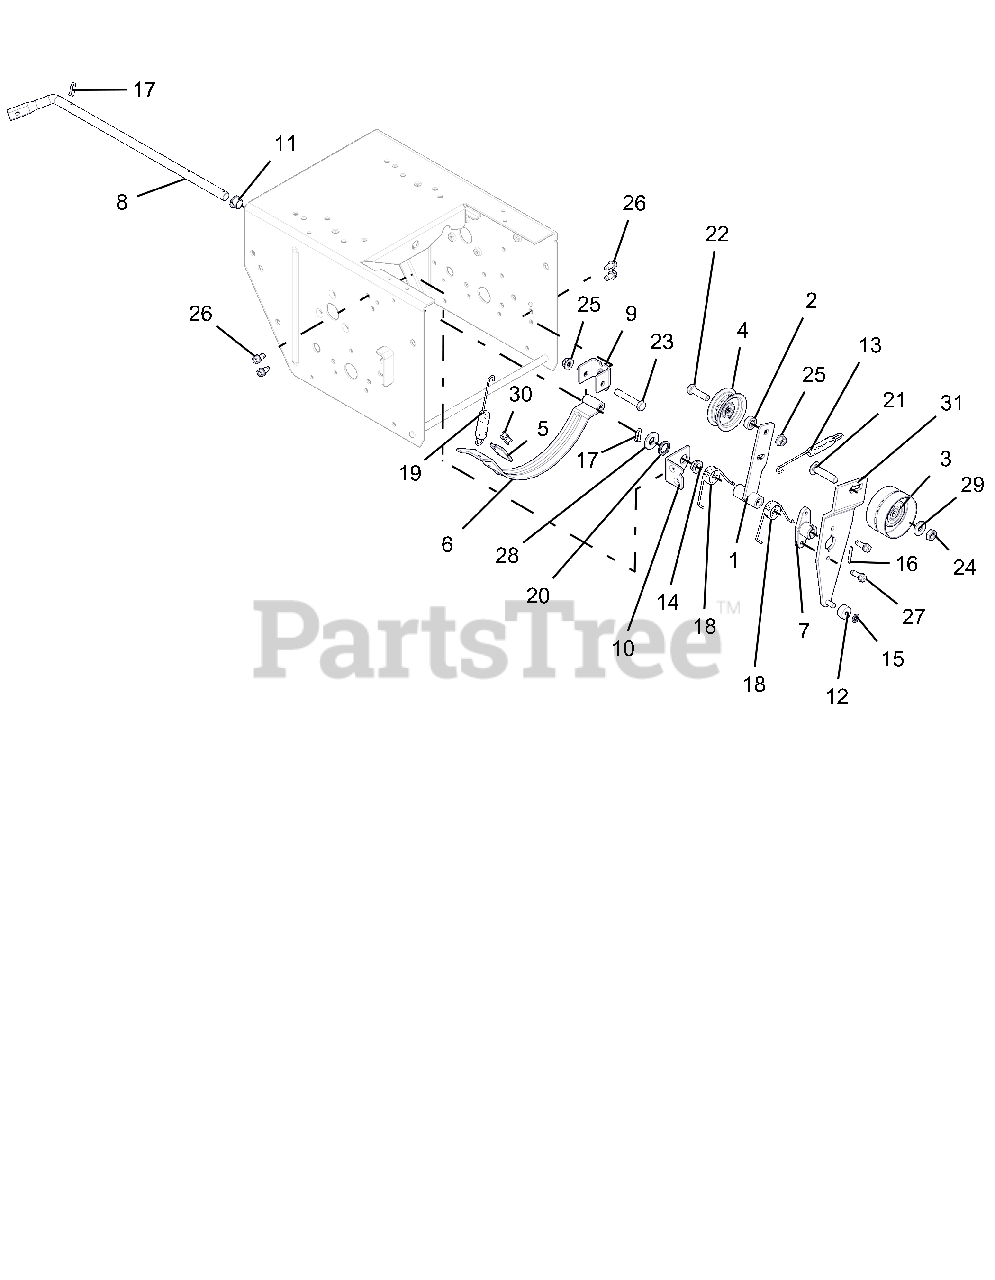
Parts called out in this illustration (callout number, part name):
1	ARM, IDLER-TRACTION
2	SPCR, BRG .315X.500X.358X.281
3	IDLER, FLAT-2.75 OD X .375 ID
4	IDLER, FLAT - 2.00"
5	PAD, BRAKE
6	ARM, BRAKE-ATTACHMENT
7	HUB, BRAKE ARM
8	ARM, ATTACHMENT
9	PIVOT, BRAKE
10	BRACKET, SUPPORT
11	BUSHING, POLYLINER-.50 SPLIT
12	BSHG,SLV .265 X .625 X .375
13	SG-TENS .06X.482X5.35
14	BSHG,FLANGE .500X.625X.270X.75
15	RG-RTNG-EXT .250X.010
16	PIN-ROLL .125X1.00
17	CLIP, SPRING
18	SG-TORS .067X.88
19	SG-TENS .056X.60X4.40
20	WAVE SPRING .600X.875X.25FH
21	@BLT-RHDSSQNK .38-16X1.75 G5YZ
22	@BLT-HEX .31-18X1.25 GR5 YWZC
23	@BLT-HEX .31-18X2.00 GR5 YWZC
24	@NUT-LK-CTR-JAM .375-16 YWZC
25	@NUT-LK-TOP-FLG .31-18 YWZC
26	SCR-TAP .25-20X.50 HWH TR YWZ
27	SCR-TAP-PM .25-20X.75 TR YWZ
28	@WSHR-FL-STL.531X1.06X.095YWZC
29	@WSHR-FL-STL.38X.875X.083 YWZC
30	RVT-POP .187 YZ
31	ARM, IDLER-ATTACHMENT
